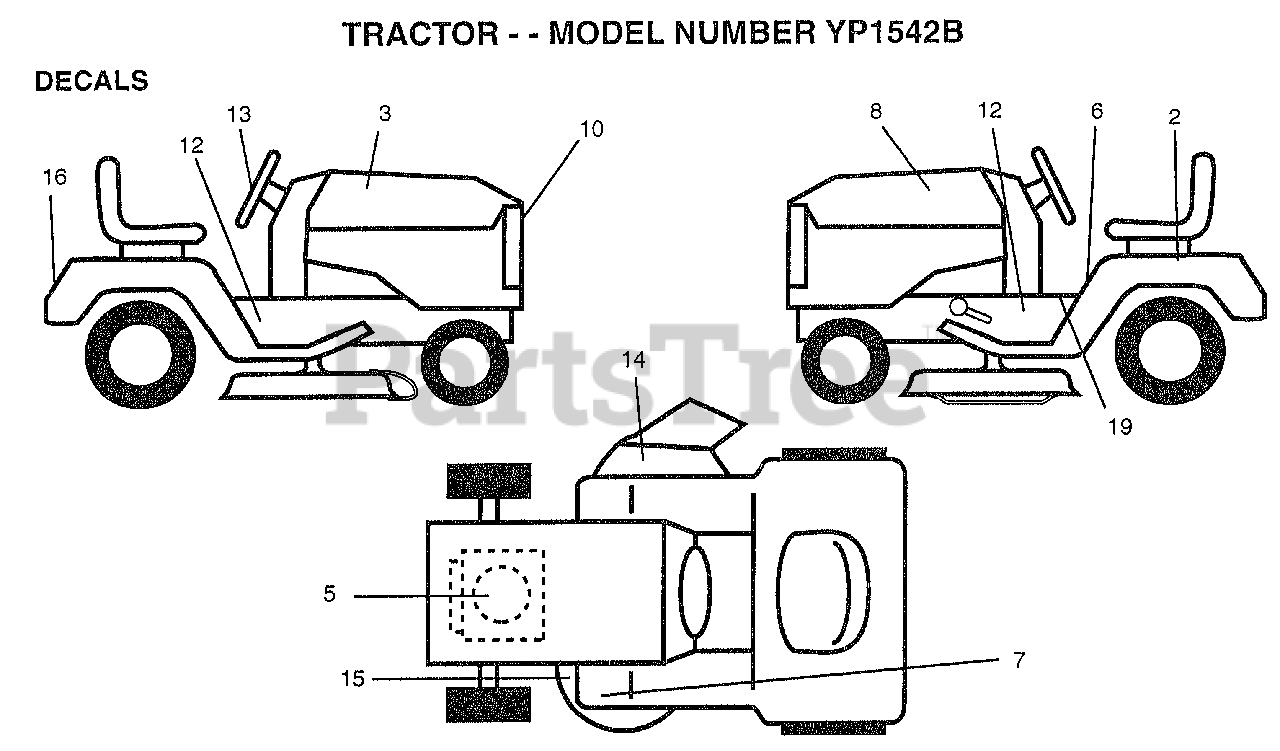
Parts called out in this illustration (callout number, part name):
2	DECAL INS STRG WH
3	"DECAL HOOD,RH"
6	DECAL.CAUT.ENG/FR
7	DECAL T
8	"DECAL HOOD,LH"
12	DECAL CHASSIS
13	DECAL INS STRG WH
14	"DECAL, WARNING"
15	"DECAL-SCHEM,BELT"
16	DECAL FENDER
19	"DECAL.OPER,SDL"
